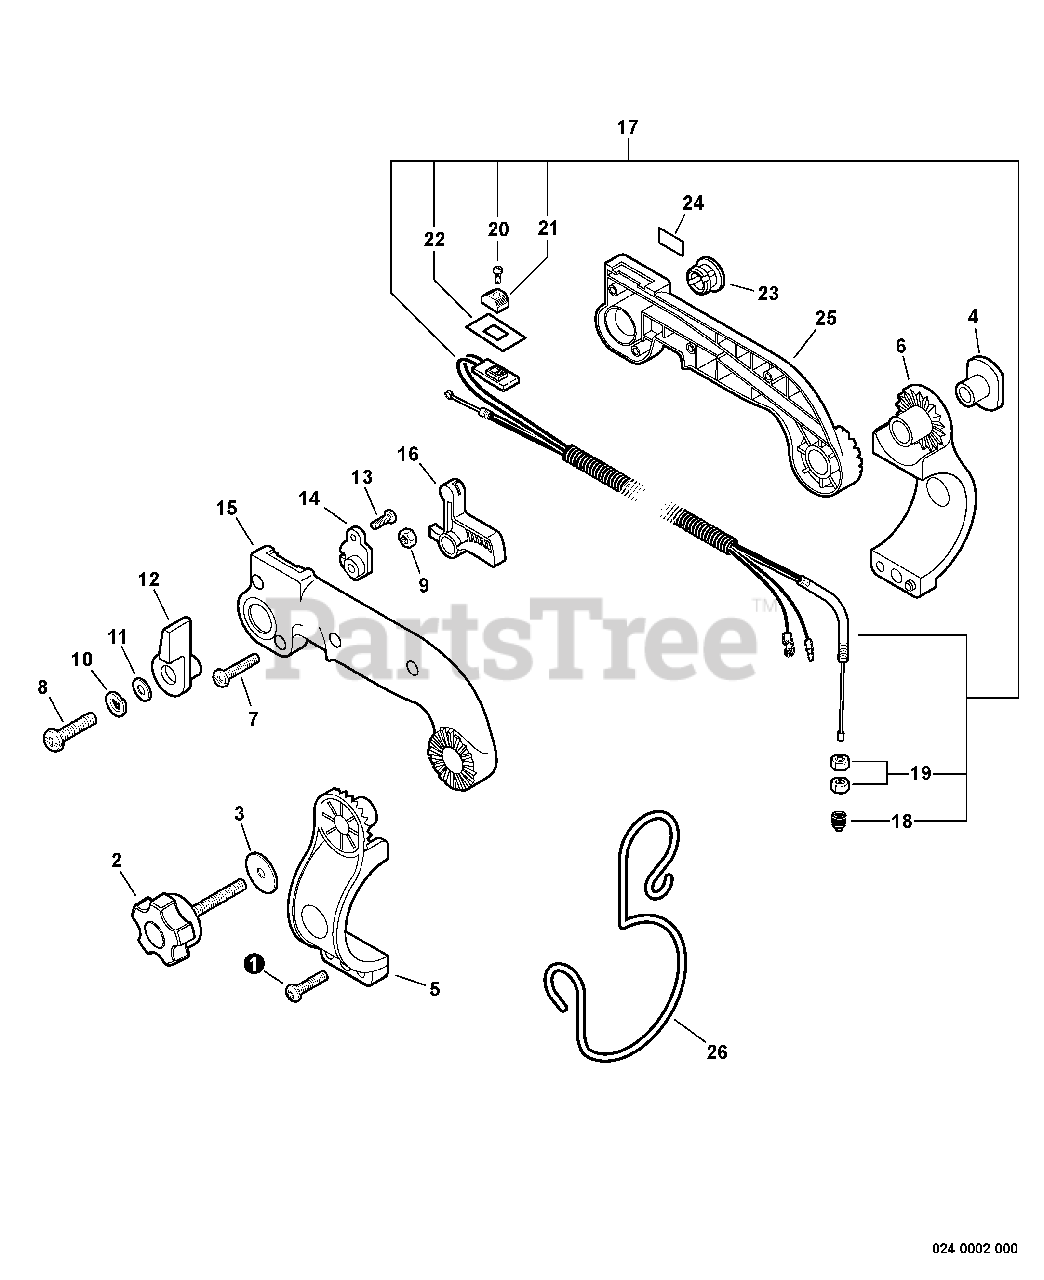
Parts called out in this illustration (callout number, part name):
1	SCREW - 5X20 -- TAPPING
2	THUMBSCREW
3	WASHER - 6
5	BRACKET, HANDLE - LEFT
6	BRACKET, HANDLE - RIGHT
7	SCREW - 5X20 -- TAPPING
8	SCREW - 6X20
9	LOCKNUT - 6
10	LOCKWASHER - 6
11	WASHER - 6
12	CONTROL, THROTTLE
13	SCREW - 4X10
14	BRACKET, THROTTLE
15	HANDLE, CONTROL - LEFT
16	TRIGGER, THROTTLE
17	CONTROL CABLE ASSY
18	CAP, DUST
20	SCREW - 3X10
21	KNOB, SWITCH - ORANGE
22	COVER, SWITCH - STOP
24	LABEL - STOP
25	HANDLE, CONTROL - RIGHT
